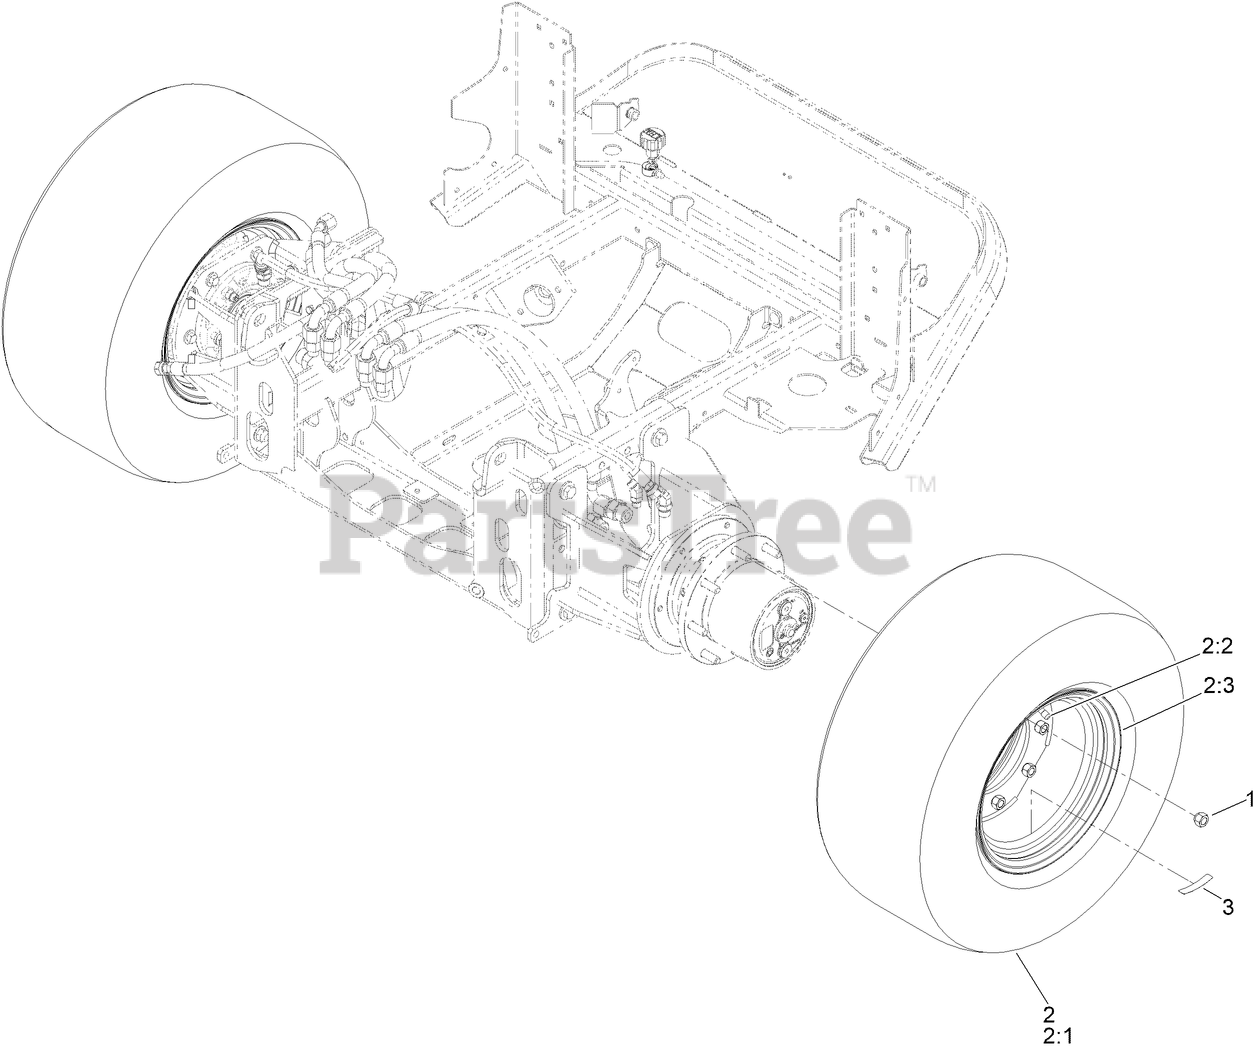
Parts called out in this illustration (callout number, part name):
1	NUT-LUG
2	ASM-TIRE 26 X 12-12
2:3	WHEEL - 12.0X8.5 8/8.0
3	DECAL-WHEEL HUB
